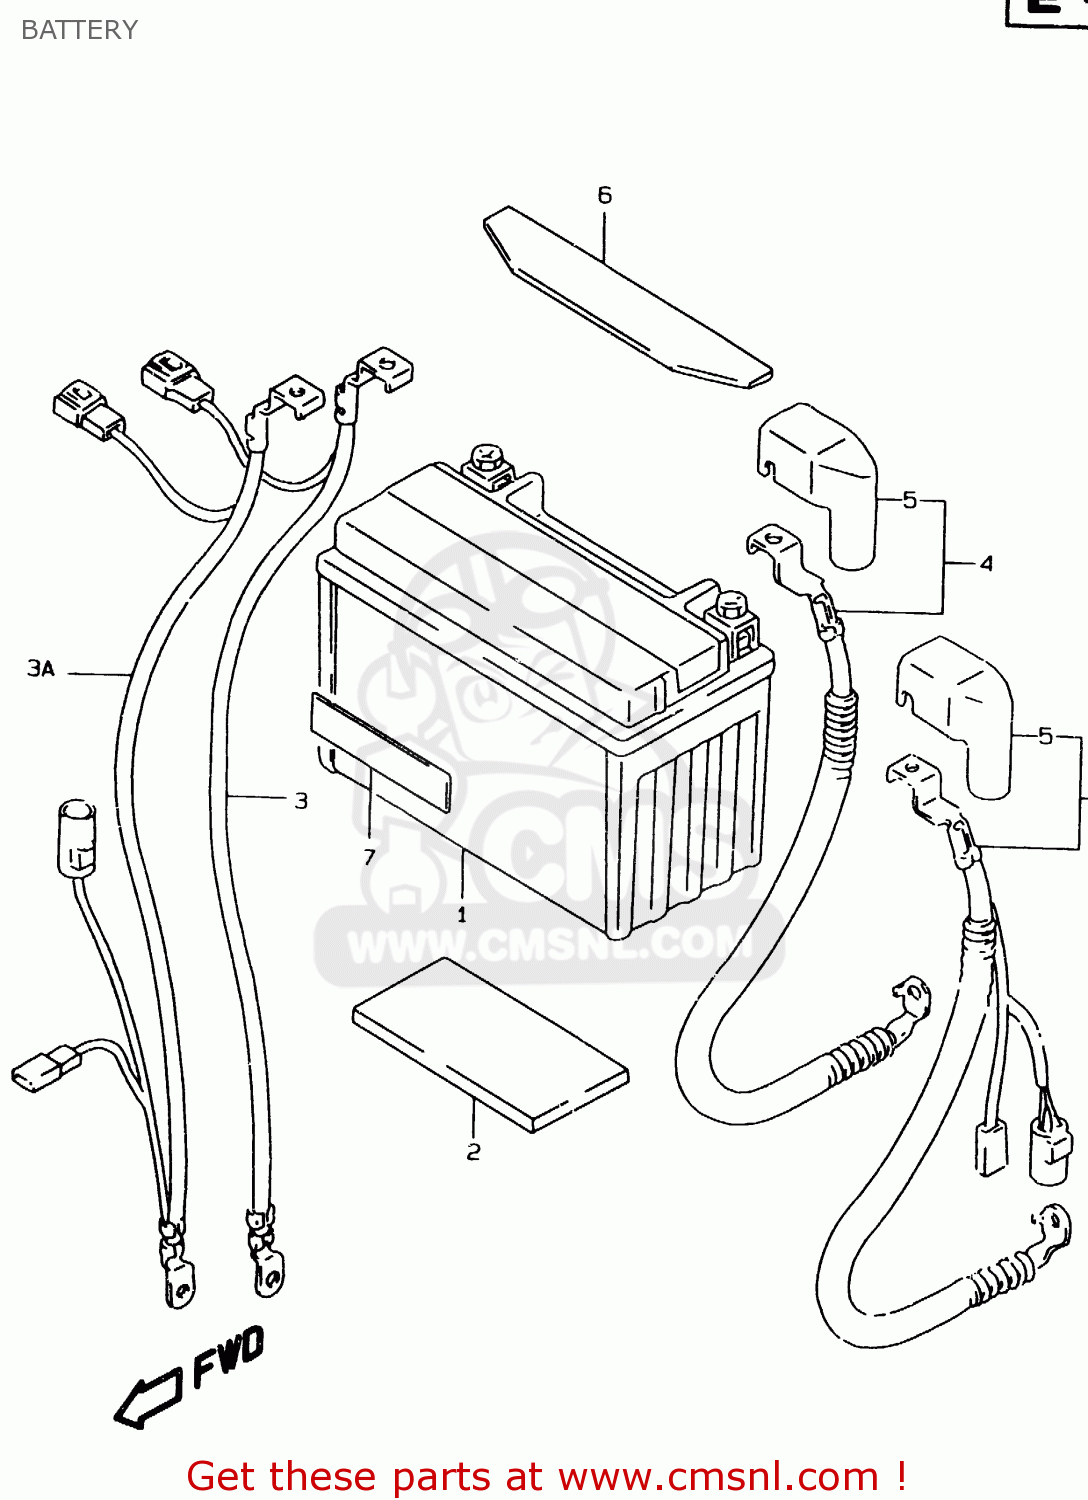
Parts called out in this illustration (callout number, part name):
1	BATTERY ASSY(YTX12-BS,12V10AH)
2	PROTECTOR(170X95X3.0)
3	WIRE,BATTERY MINUS
3A	WIRE,BATTERY MINUS
4	WIRE,BATTERY PLUS LEAD
4A	WIRE,BATTERY PLUS
5	CAP,BATTERY PLUS TERMINAL
6	PROTECTOR,BATTERY
7	PROTECTOR(20X90)X1.0
